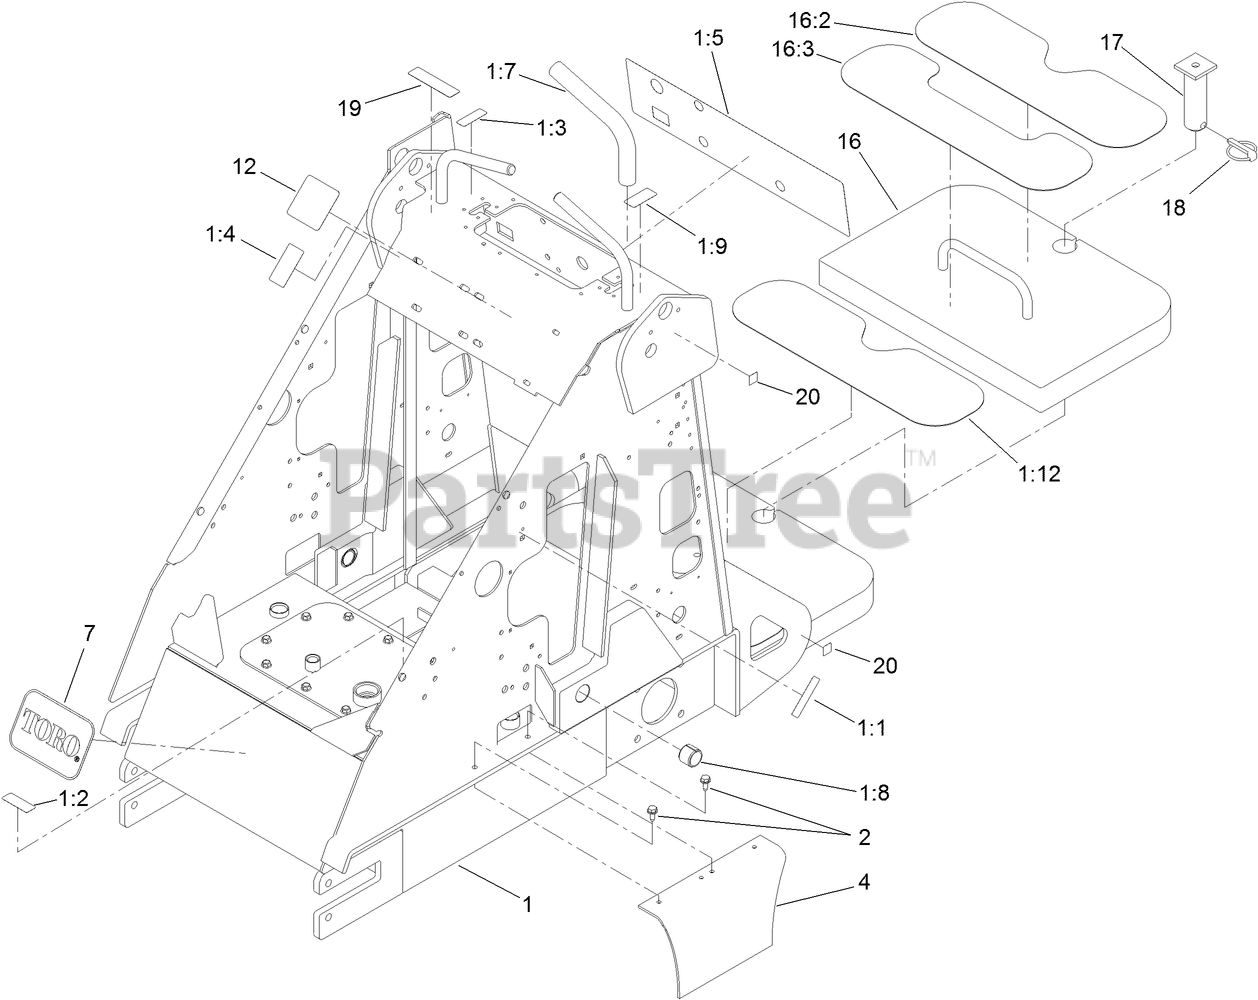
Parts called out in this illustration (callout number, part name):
1	FRAME ASM
1:1	DECAL-PINCH
1:2	DECAL-OIL, HYD
1:3	DECAL-CHOKE
1:4	DECAL-POWER, AUXILIARY
1:5	DECAL-PANEL, CONTROL
1:7	GRIP-CUSHION
1:8	BUSHING-TENSION
1:9	DECAL-THROTTLE
1:12	TREAD-FOOT
2	SCREW-HWHTF
4	COVER-CHAIN
7	DECAL
12	DECAL-SELECTOR, SPEED
16	COUNTERWEIGHT ASM
16:2	TREAD-FOOT
18	PIN-LYNCH
19	DECAL-ARRESTER, SPARK
20	DECAL-POINT, LIFT
